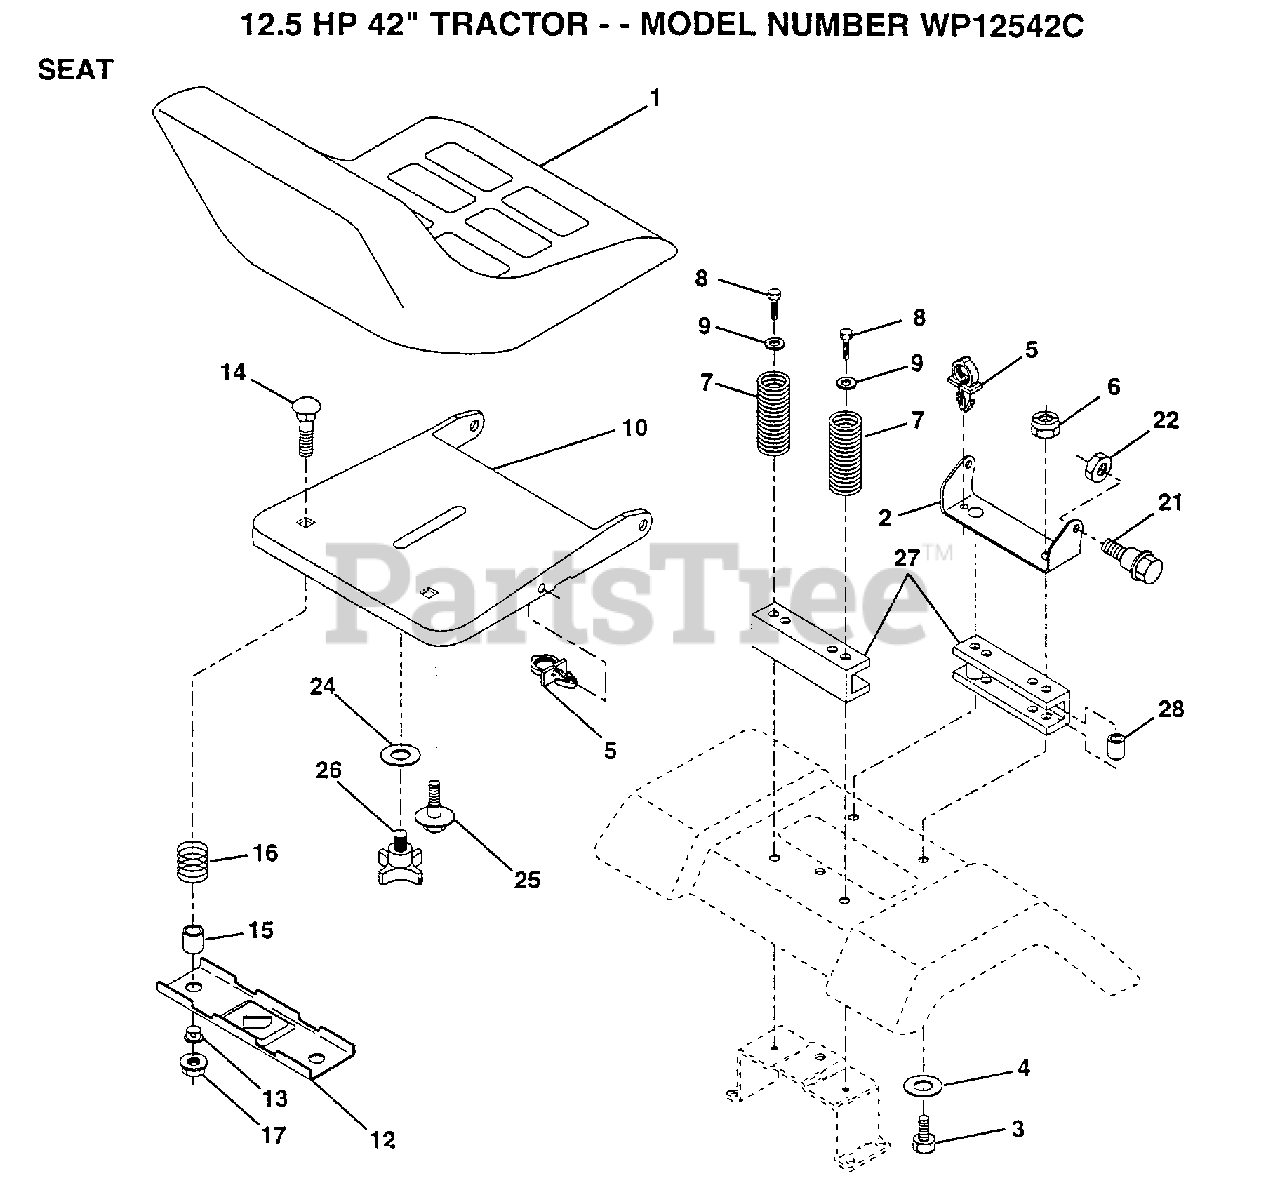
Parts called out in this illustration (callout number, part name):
2	BRACKET PVT SEAT
3	BOLT
4	WASHER PM
5	CLIP PUSH - IN
6	NUT
7	SPRING COMPRESSIO
8	SCREW
9	WASHER
12	BRKT SWITCH
13	BUSHING
15	SPLIT SPACER
16	SPRING
21	BOLT.SHLD.5/16-18
22	NUT
24	WASHER
25	"BOLT,SHOULDER"
26	"KNOB 1/2"" YT"
27	SEAT SPACER
28	SPLIT SPACER
